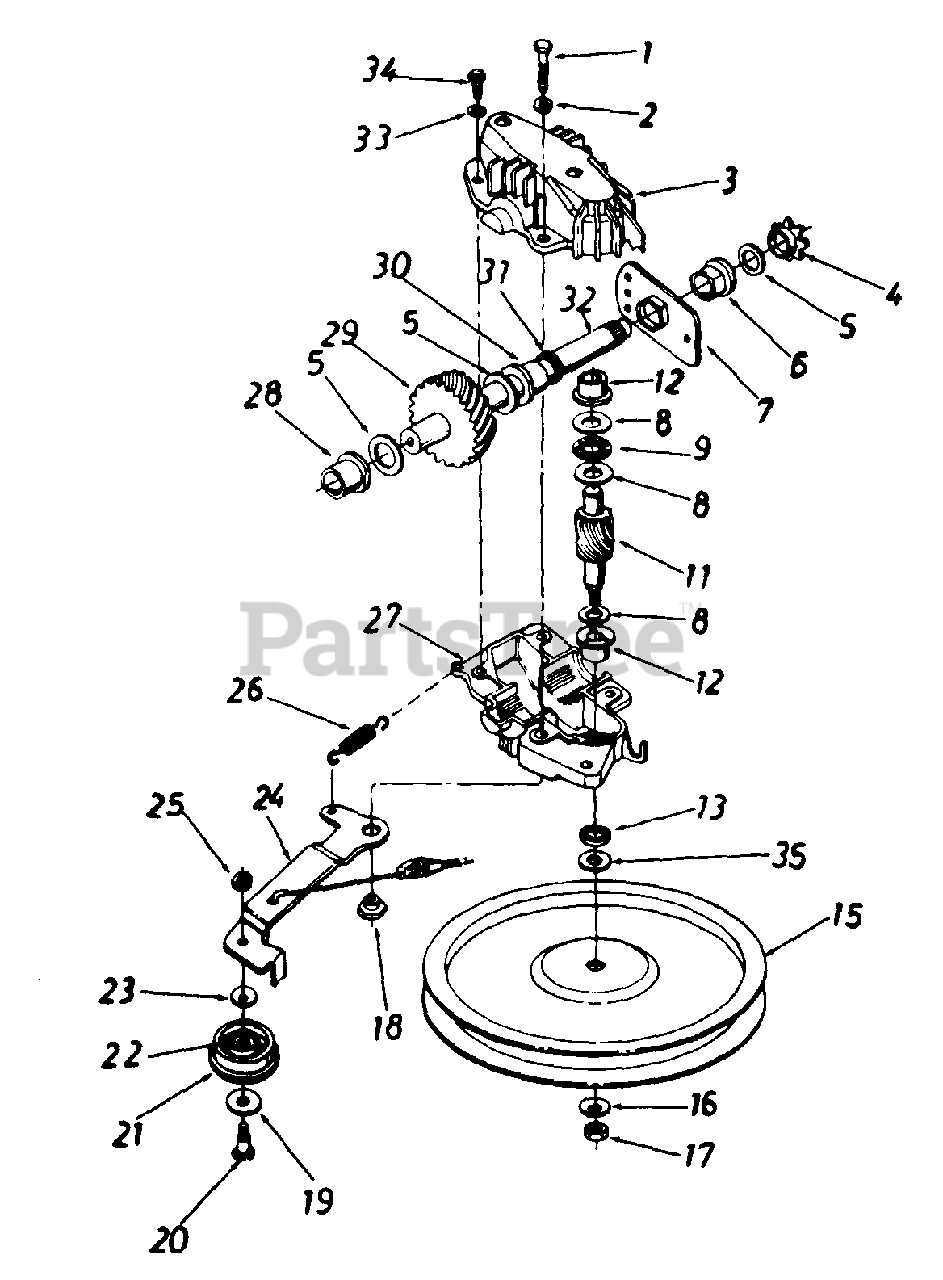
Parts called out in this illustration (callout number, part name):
1	Hex Bolt 1/4-20 x 1.25" Lg. w/Patch
2	L-Wash. 1/4" I.D.
3	Upper Hsg. Half
4	#48 Sprocket 7 Tooth x 1/2 Pitch
5	Fl-Wash. 5/8" I.D. x .030
6	Hex Flange Brg..631" I.D.
8	Thrust Wash..382" I.D. x .70" O.D.
9	Thrust Bearing .375" I.D. x .812" O.D
11	11 Tooth Pinion Shaft
12	Flange Bearing
13	Oil Seal
15	Fl-Pulley 5.06" O.D.
16	Bell-Wash..265" I.D. x .75"
17	Hex L-Nut 1/4-28 L.H. Thd.
18	Shld. Spacer .375" Dia. x .170
19	Fl-Wash, .390" I.D. x 1.0"
20	Shld. Bolt .375" Dia. x .40"
21	Fl-Idler Plastic 1.50" Dia.
22	Needle Brg..375" x .31
23	Bell-Wash..265" I.D. x .75"
24	Idler Brk't. Ass'y.
25	Hex Patch L-Nut 1/4-28 Thd.
26	Extension Spring 1.12" Lg.
27	Lower Hsg. Half
28	Flange Bearing .566 Dia.
29	33 Tooth Helical Gear
30	Flange Bearing .629 Dia.
31	Oil Seal .625 Dia.
32	Gear Sprocket Shaft
33	L-Wash. #10 I.D.
34	Hex B-Tap Scr. #10 x .62"
35	Hex Washer .26" x .88"
